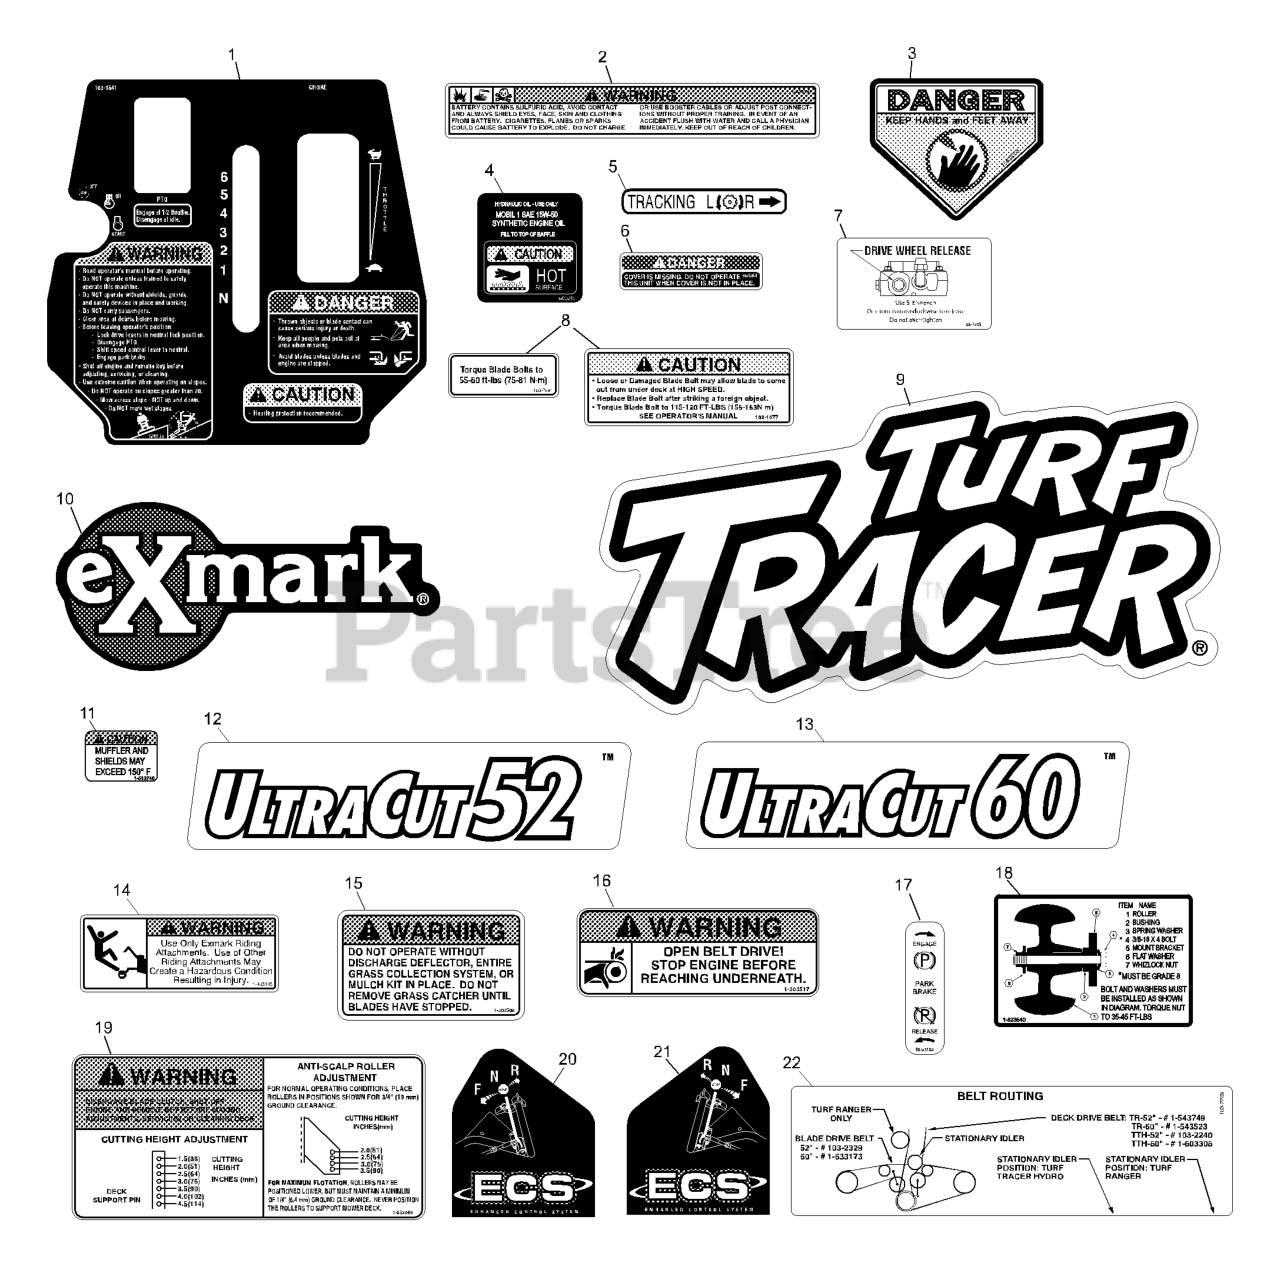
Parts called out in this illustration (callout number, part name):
1	DECAL,TTH ECS CONSOLE
2	DECAL-BATTERY
3	DECAL-DANGER
5	DECAL,TRACKING ADJUST
6	DECAL-COVER, MISSING
7	DECAL,DRIVE RELEASE
8	DECAL,BOLT TORQUE
9	DECAL,TTH MODEL
10	DECAL,EXMARK LOGO
12	DECAL,ULTRACUT 52
13	DECAL,ULTRACUT 60
14	DECAL,SULKY WARNING
15	DECAL-WARNING, DISCHARGE
16	DECAL,BELT DRIVE
17	DECAL,PARKING BRAKE
18	DECAL,ROLLER MOUNTING
19	DECAL,ANTI SCALP
20	DECAL,LH ECS INSTRUCTION
21	DECAL,RH ECS INSTRUCTION
22	DECAL,BELT ROUTING
